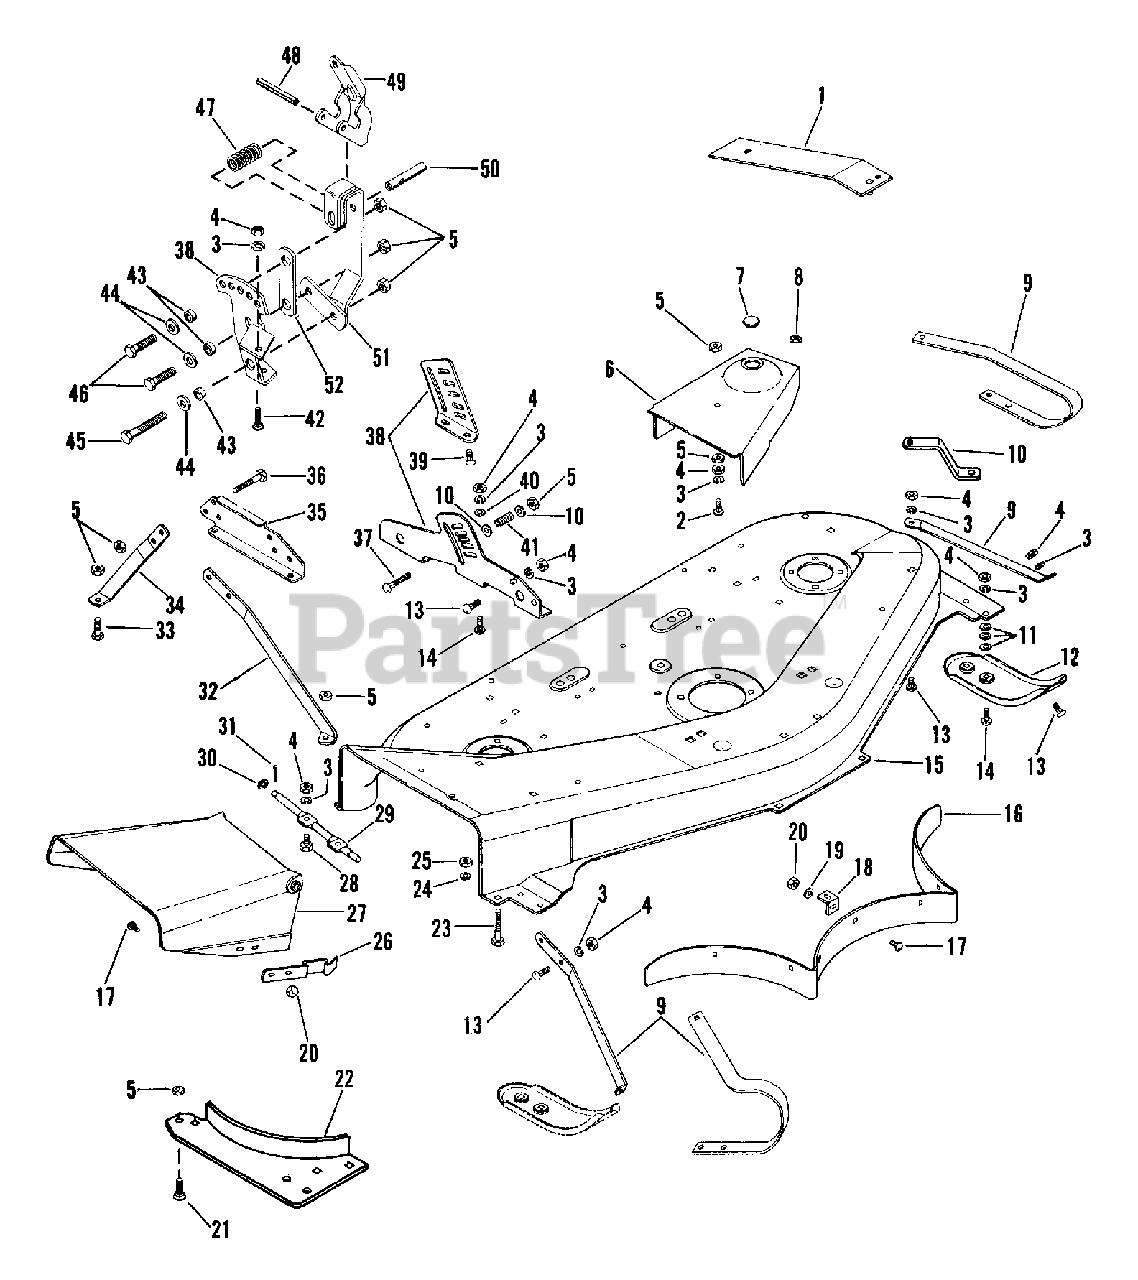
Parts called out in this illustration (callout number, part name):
2	BLT-RDHDSQNK .31-18X3.25 SHTPL
2	BLT-RDHDSQNK .31-18X.75 GR5 PL
3	WSHR-LK .312X.097 PL HVY
4	NUT-HEX .312-18
5	NUT-LK .312-18 GR A PL
6	LH BELT COVER
6	RH BELT COVER
6	BELT COVER-RH
6	BELT COVER LH
6	BELT COVER R.H.
6	BELT COVER L.H.
7	BUTTON PLUG 1.0
8	NUT-LK-NYL.312-18 PL
9	BRACE
9	SKID BRACE-RH
9	SKID BRACE LH
9	SKID BAR L.H.
9	SKID BAR R.H.
10	BRACE
11	WSHR-FL-STL .38X.875X.083 PL
12	SKID
13	BLT-RDHDSQNK .31-18X.75 GR5 PL
14	BLT-RDHDSQNK .31-18X1.00 PL
14	BLT-RDHDSQNK .31-18X1.50 PL
15	48 INCH MOWER PAN W/DECALS
15	42 INCH MOWER PAN W/DECALS
15	MOWER PAN W/DECALS 48"- ORANGE
15	60 INCH MOWER PAN W/ DECALS
15	MOWER PAN W/DECALS 42"
16	BAFFLE
16	BAFFLE-42 IN PAN
17	BLT-RDHDSQNK .25-20X.50 SHT PL
18	BAFFLE TAB
19	WSHR-FL-STL.281X.62X.065 PL
20	NUT-LK-CTR .250-20 PL
21	BLT-RDHDSQNK .312-18X.62 PL
22	TOE GUARD
22	DEFLECTOR
23	BLT-HEX.38-16X2.5FTHD GR2 YWZC
23	BLT-RDHDSQNK .38-16X2.00 SHTYW
24	WSHR-LK .375X.115 HVY PL
25	NUT-HEX .375-16
26	SPRING, FLAT
27	CHUTE EXTENSION
28	BLT-HEX .31-18X.75 PL GR5
29	HINGE PIN
30	WSHR-FL-STL.406X.812X.065PL
31	PIN-COTR .09X.75 PL
32	BRACE-RIGHT FRONT
33	BLT-RDHDSQNK .312-18X.62 PL
34	BRACE-RIGHT REAR
35	BRACKET-BRACE
36	BLT-HEX .31-18X.75 PL GR2
37	BLT-RDHDSQNK .31-18X1.75 PL
38	HEIGHT QUADRANT
38	QUADRANT
39	BLT-RDHDSQNK.31-18X.75GR5SHTPL
40	WSHR-FL-STL .323X.625X.062 PL
41	SG-COMP .063X.53X1.187
42	BLT-SERRDHD SL .31-18X.75 YZ
43	SPACER BUSHING .5 X .32 X .21
44	WSHR-FL-STL .328X.875X.062 PL
45	BLT-HEX .31-18X1.25 PL GR5
46	BLT-HEX .31-18X.75 PL GR2
47	SG-COMP .045X.50X1.187
48	PIN-ROLL .188X1.75
49	LEVER
50	PIN
51	HANDLE HEIGHT ADJ.
52	LINK
